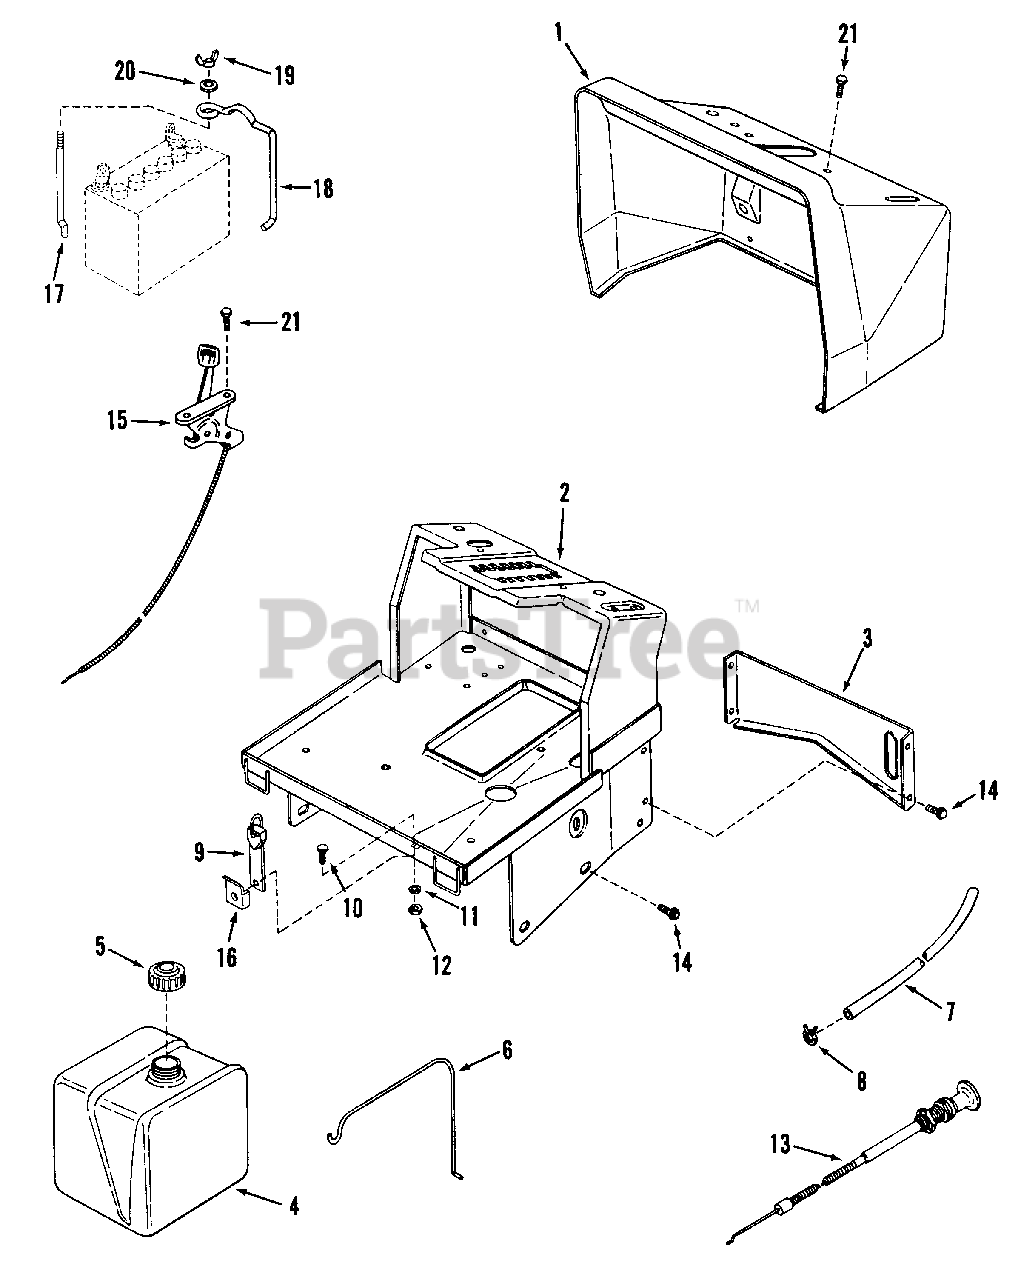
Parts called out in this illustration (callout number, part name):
1	PANEL, Dash
2	PEDESTAL
3	BRACKET, Lower Dash
4	TANK, Fuel 5 Qt.
5	CAP, Fuel Tank Filler
6	HOLD-DOWN, Fuel Tank
7	LINE, Fuel (12-1/2" Long)
8	CLAMP, Fuel Line
9	STRAP, Tank Hold Down
10	BOLT, 1/4-20 x 5/8" Flat Head Carriage, Grade 2
11	WASHER, 1/4 SAE
12	NUT, 1/4-20 Hex Flange Lock, Grade 5
13	CONTROL, Choke Cable (29")
14	SCREW, 5/16-18 x 5/8" Hex Washer Self-Tap
15	CONTROL, Throttle (27-3/4")
15	CONTROL, Throttle (30.0")(B&S Twin 2)
16	CLIP, Hood Retainer
17	HOLD-DOWN, Battery
18	CLAMP, Battery
19	WING-NUT, 1/4-20
20	WASHER, 1/4 Flat
21	SCREW, #10-24 x 1/2" Hex Washer Self-Tap
